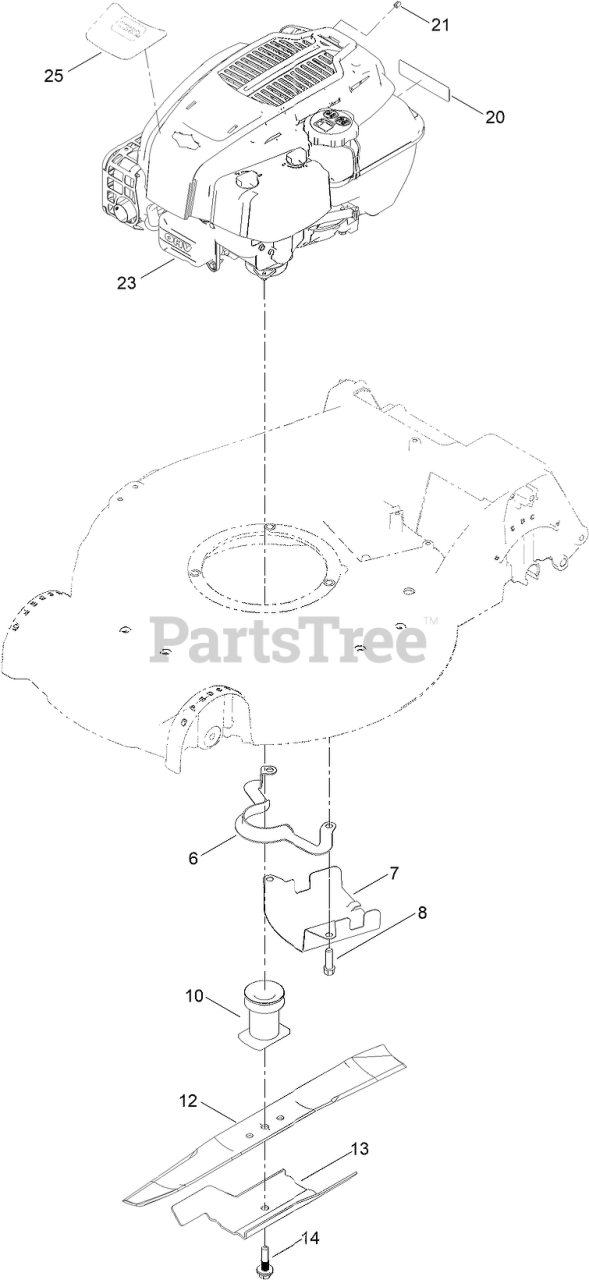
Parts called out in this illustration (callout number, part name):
6	GUIDE-BELT
7	SHIELD-GRASS
8	SCREW-TAPTITE
10	DRIVER-BLADE
12	BLADE-21IN, RECYCLING
13	ACCELERATOR-BLADE
14	BOLT-BLADE
20	DECAL-ARRESTOR, SPARK
21	STOP-ROPE
23	ENGINE-BRIGGS 875 ES SS
25	DECAL-ENGINE
